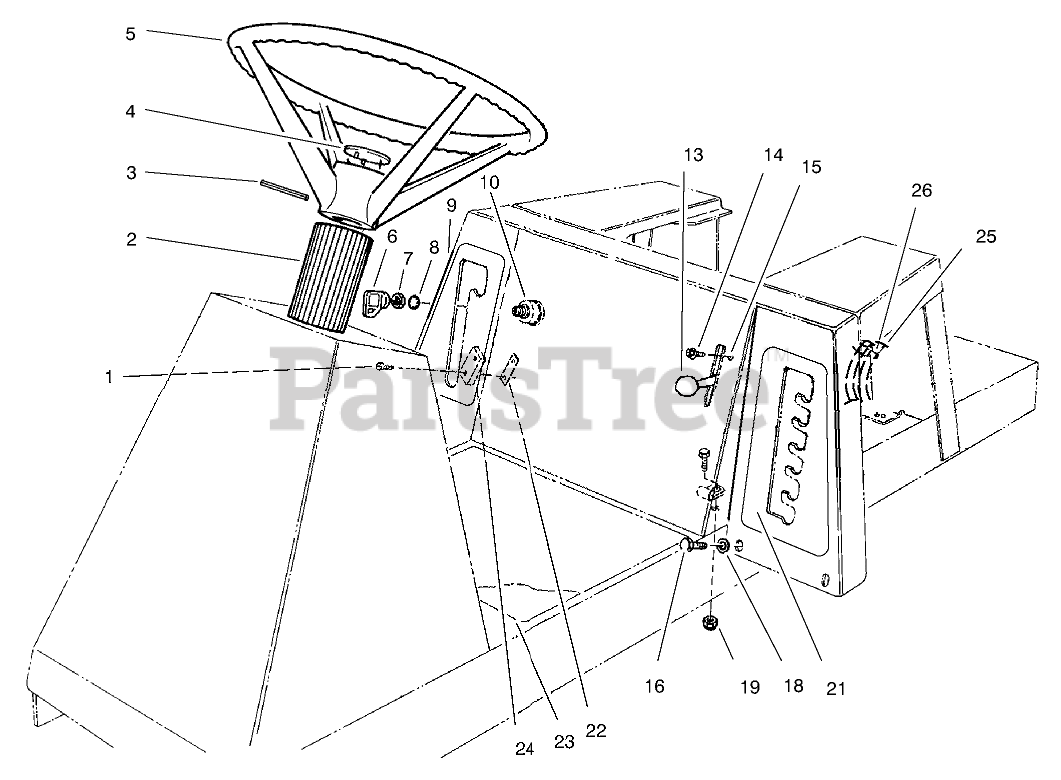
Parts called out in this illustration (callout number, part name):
1	SCREW-PPHTF
2	COVER-STEERING SHAFT
3	PIN-ROLL
4	INSERT - STRG WHL F/W
5	Assy.-Wheel, Steering (Incl. Ref. #4)
6	KEY-IGNITION
7	NUT-HH
8	WASHER-TOOTH, INTERNAL
9	DECAL - DECK ENGAGE
10	Switch-Ignition (Incl. Ref. #7-8)
13	KNOB-CONTROL
14	SCREW-HWHTF
15	Control-Throttle (Incl. Ref. #13)
16	SCREW-HH
18	WASHER-PLAIN
19	NUT-LOCK, NI
21	DECAL - HOC
22	NUT-SPEED
23	DECAL - INSTRUCTION
24	SWITCH-MICRO
25	WIRE ASM
26	TIE-CABLE
